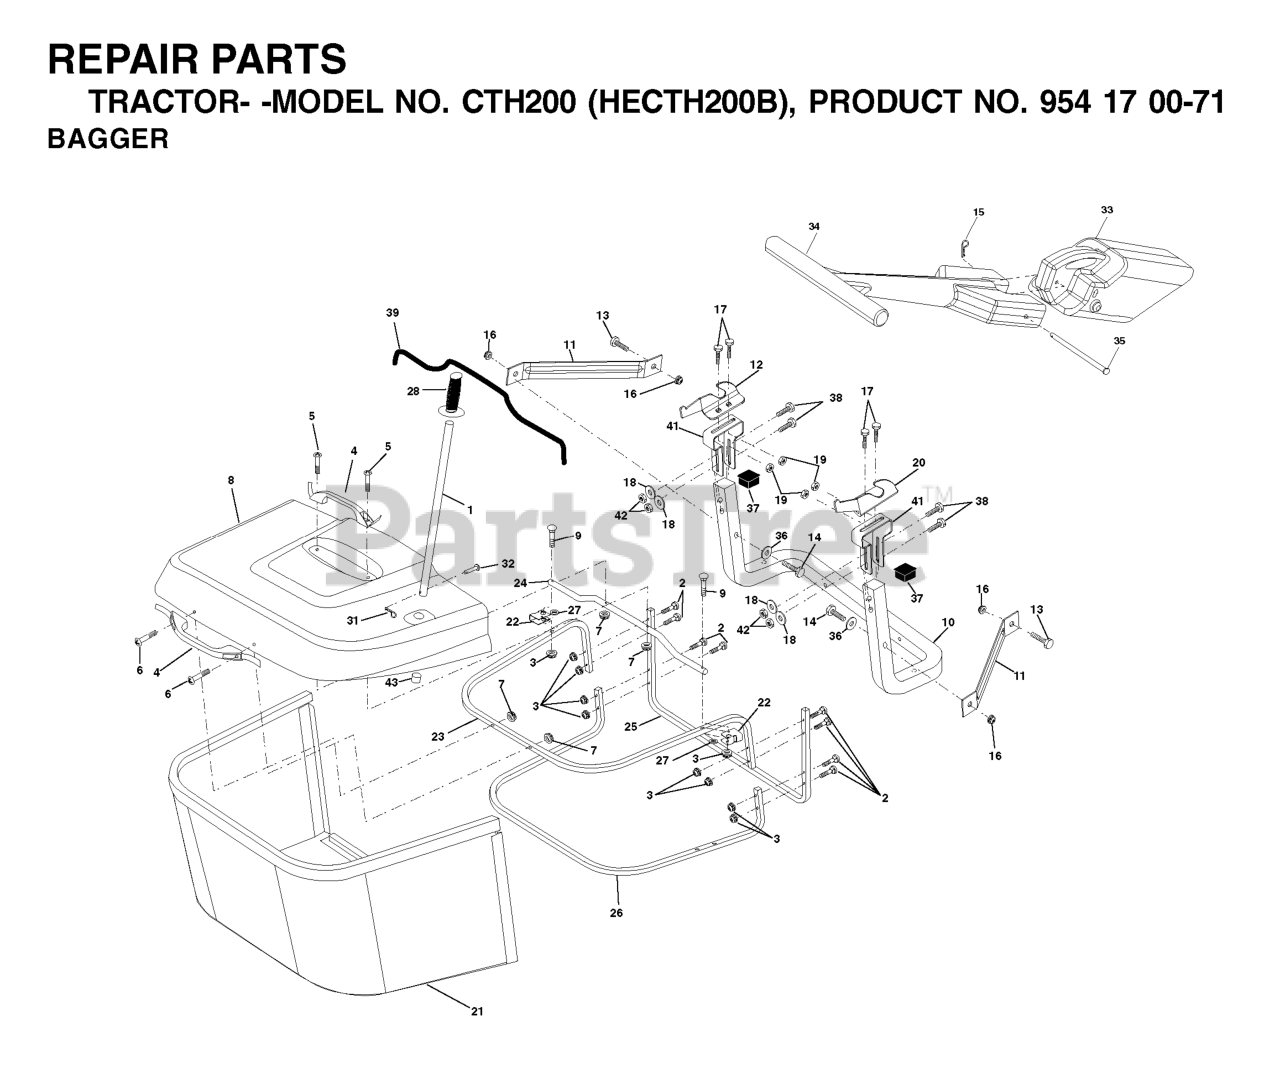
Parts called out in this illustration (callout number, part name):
1	TUBE HANDLE
2	Bolt Carriage 1/4-20 x 2.0 Gr.5
3	NUT T
4	HANDLE.BAGGER.W/LVRS.BLK.CRD
5	SCREW.PAN.HEAD
6	REPL BY 532 75 00-29
8	COVER.PNT.BGR.CRD.WSLOTS.MS668
9	Bolt Carriage 1/4-20 x 2.25d x Gr.5
10	TUBE
11	BRACKET.SUPPORT.UPPER.BAG.CRD
14	BOLT-HEX EAK
15	RETAINER-SPRNG RB
16	NUT LOCK FLG 3/8-16 UNC
17	RP BOLT 5/16-18 X3/4 ZN/YEL GR
18	WASHER M
19	NUT LOCK HEX FLANGE 5/16-18
20	BRACKET
21	GRASS BAG
22	BRKT.SIDE.BAG.CRD
23	TUBE.UPPER.BAG.CRD
24	TUBE.PIVOT.BAG.CRD.BLACK
26	TUBE.LOWER.BAG.CRD
28	GRIP.HANDLE.BLACK
31	RETAINER M
32	RIVET,DRILLED
33	MULCH PLUG, CTH150
34	HANDLE.MULCHER.92.CRD (2 2)
36	WASHER
37	Plug Support Bagger CRD
38	BOLT.5/16-18X2.5
39	SEAL.TRIM.37'
41	BRKT.VERT.ADJ.BAGGER.CRD
42	NUT.71038.31-18.HEX.NYLOCK
43	PLUG, TUBING END
